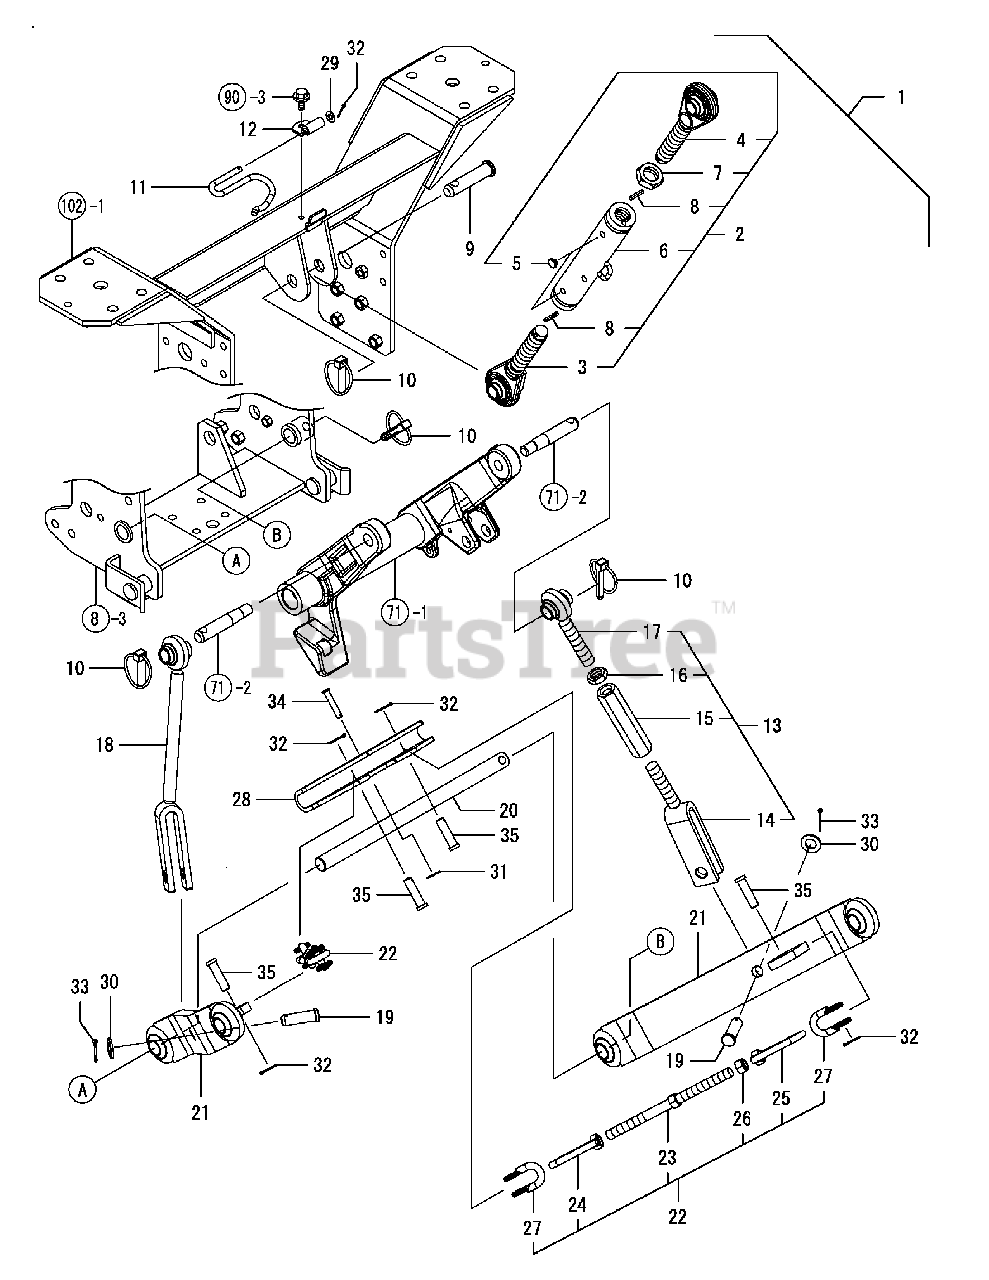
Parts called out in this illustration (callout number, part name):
1	3P LINK KIT
3	EYEBOLT ASSY, L
4	EYEBOLT ASSY, R
6	TURNBACKLE ASSY
8	SPRING PIN 5X25
9	PIN, UPPER LINK
10	PIN ASSY, LINTCH
12	PLATE (TOPLINK)
13	ROD CMP, LIFT R
14	END ASSY, LOWER
17	END ASSY, UPPER
18	ROD CMP, LIFT L.H.
20	BAR, LOWER LINK
21	LINK ASSY, LOWER
22	CHAIN ASSY, CHECK
23	TURNBACKLE ASSY
24	EYENUT, CHAIN L
25	EYENUT, CHAIN R
29	WASHER 8, POLISHED
30	WASHER 16, POLISHED
31	SNAP PIN (JASO 8)
32	COTTER PIN 2.5X25
33	COTTER PIN 3.2X32
35	PIN, H12X40
